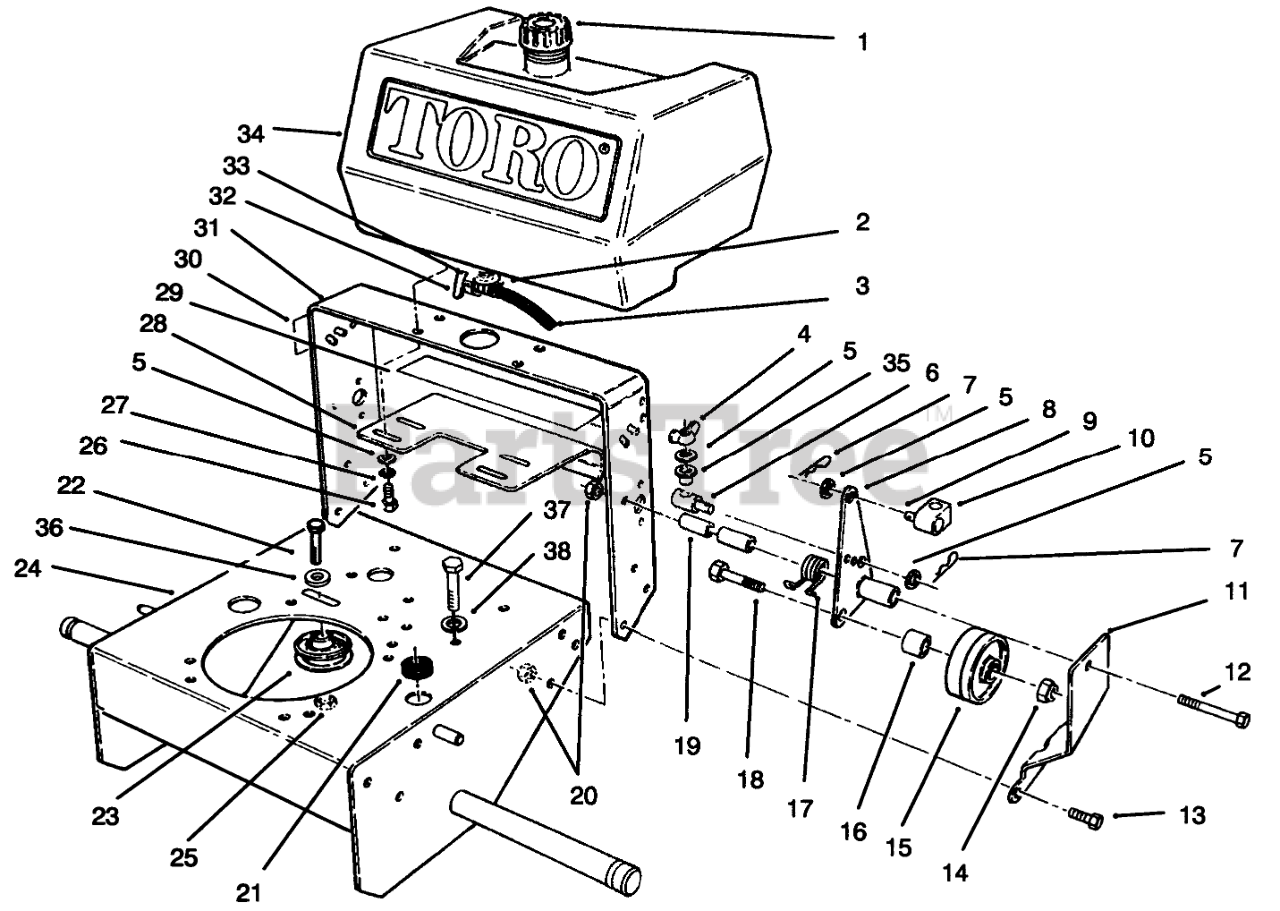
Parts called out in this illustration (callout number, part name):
1	GAS CAP ASM
2	CLAMP-HOSE
3	HOSE-FUEL
4	NUT-WING
5	WASHER-PLAIN
6	FITTING-ROD
7	PIN-COTTER
8	BRACKET-Idler, LH
9	PIN-CLEVIS
10	FITTING-ROD
11	Bracket-LH
12	SCREW-HH
13	SCREW-HH
14	NUT-LOCK, NI
15	IdlerWheel
16	WHEEL IDLER SPACER
17	SPRING-TORSION, LH
18	SCREW-LEVELER
19	SPACER-PIVOT, IDLER
20	NUT-LOCK, NI
21	GROMMET
22	SCREW-HH
23	PULLEY-IDLER
24	Frame
25	NUT-HF
26	SCREW-HH
27	WASHER-LOCK
28	Plate
29	DECAL-GROUND SPEED
30	DECAL-FUEL SHUT OFF
31	Frame Rear
32	VALVE-FUEL
33	O-RING
34	Fuel Tank Assembly (Incl. Ref. # 32 & 33)
35	BUSHING-NYLON
36	WASHER-FLAT
37	SCREW
38	WASHER-LOCK/EXT
